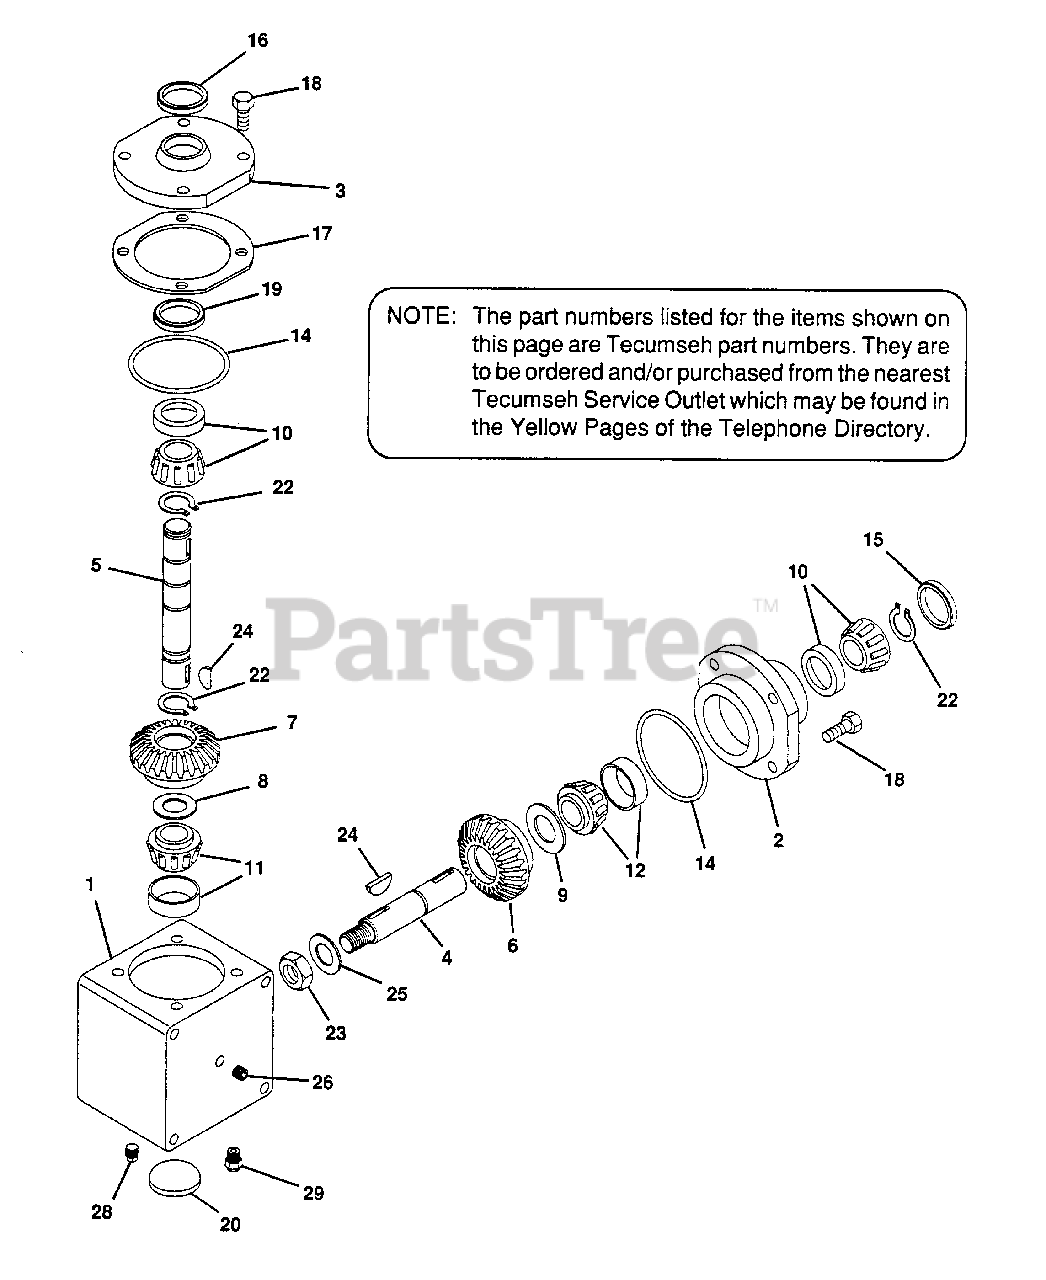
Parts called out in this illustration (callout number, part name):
1	HOUSING, RIGHT ANGLE DRIVE
2	CAP, RETAINER
3	CAP, RETAINER
4	SHAFT, INPUT(5.38" LONG)
5	SHAFT, OUTPUT(7.89" LONG)
6	GEAR, SPIRAL BEVEL(25 TEETH)
7	GEAR, SPIRAL BEVEL(26 TEETH)
8	SHIM(1-1/2" O.D. X 1-1/64" I.D.X.002 THICK)(USE AS REQUIRED)
9	SHIM(2.000" O.D.X1.531"I.D.X.002 THICK)(USE AS REQUIRED)
10	BEARING & CUP ASSY
11	BEARING & CUP ASSY
12	BEARING & CUP ASSY.
14	"O" RING
15	SEAL, OIL
16	SEAL, OIL
17	SHIM,CAP RETAINER
18	SCREW, HEX HEAD, SEMS, 5/16-18X1
19	RING, LOAD
22	RING, RETAINING
23	JAM NUT, 3/4-16
24	KEY, WOODRUFF
25	WASHER, FLAT
26	PLUG, PIPE 1/4-18
28	PLUG, PIPE 1/8-27
29	VALVE, RELIEF
